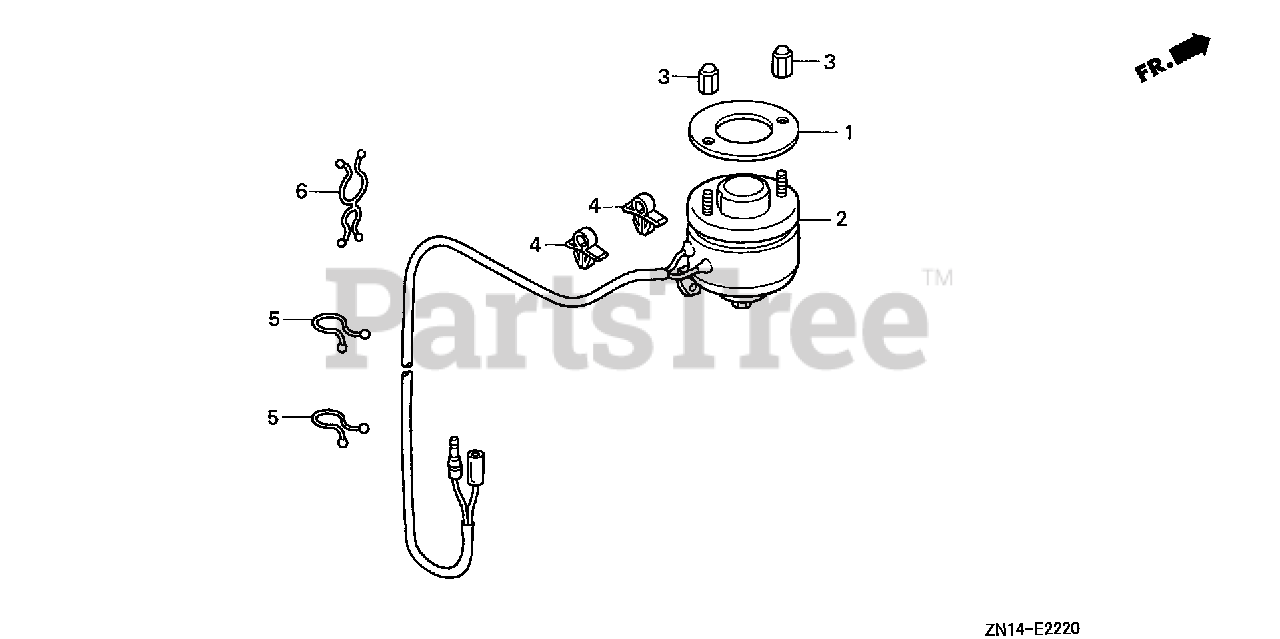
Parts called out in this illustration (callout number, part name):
1	PLATE, SOLENOID
2	SOLENOID ASSY., ROTARY
3	NUT, SPECIAL CAP
4	CLIP, WIRE HARNESS (6MM) (WHITE)
5	CLIP, PURSE LOCK (8MM)
6	CLIP, PURSE LOCK
